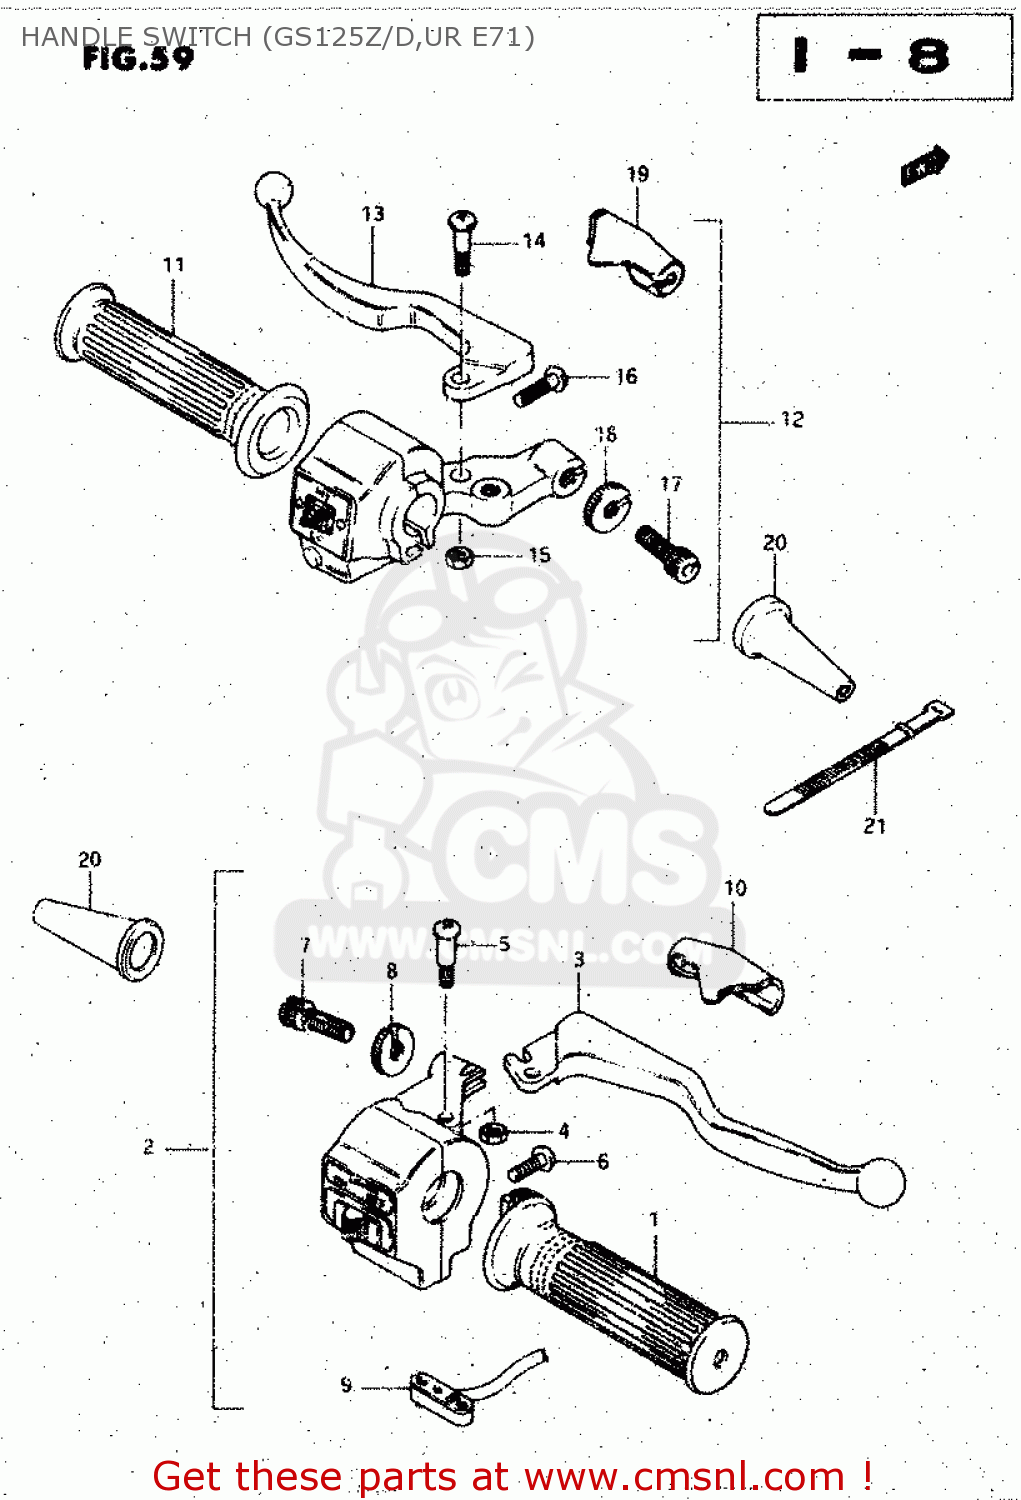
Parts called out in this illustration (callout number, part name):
1	GRIP,THROTTLE
2	BRAKE LEVER & SWITCH
3	LEVER,BRAKE
4	NUT 8MM
5	SCREW
6	SCREW 5X20
7	ADJUSTER,CABLE
8	NUT,CABLE ADJUSTER
9	SWITCH ASSEMBLY
10	COVER,BRAKE LEVER DUST
11	GRIP,L
12	LEVER ASSY,CLUTCH
13	LEVER,CLUTCH
14	SCREW
15	NUT
16	SCREW 5X20
17	ADJUSTER,CABLE
18	NUT,CABLE ADJUSTER
19	COVER,CLUTCH LEVER
20	BOOT,CLUTCH CABLE
21	CLAMP(L:120)
